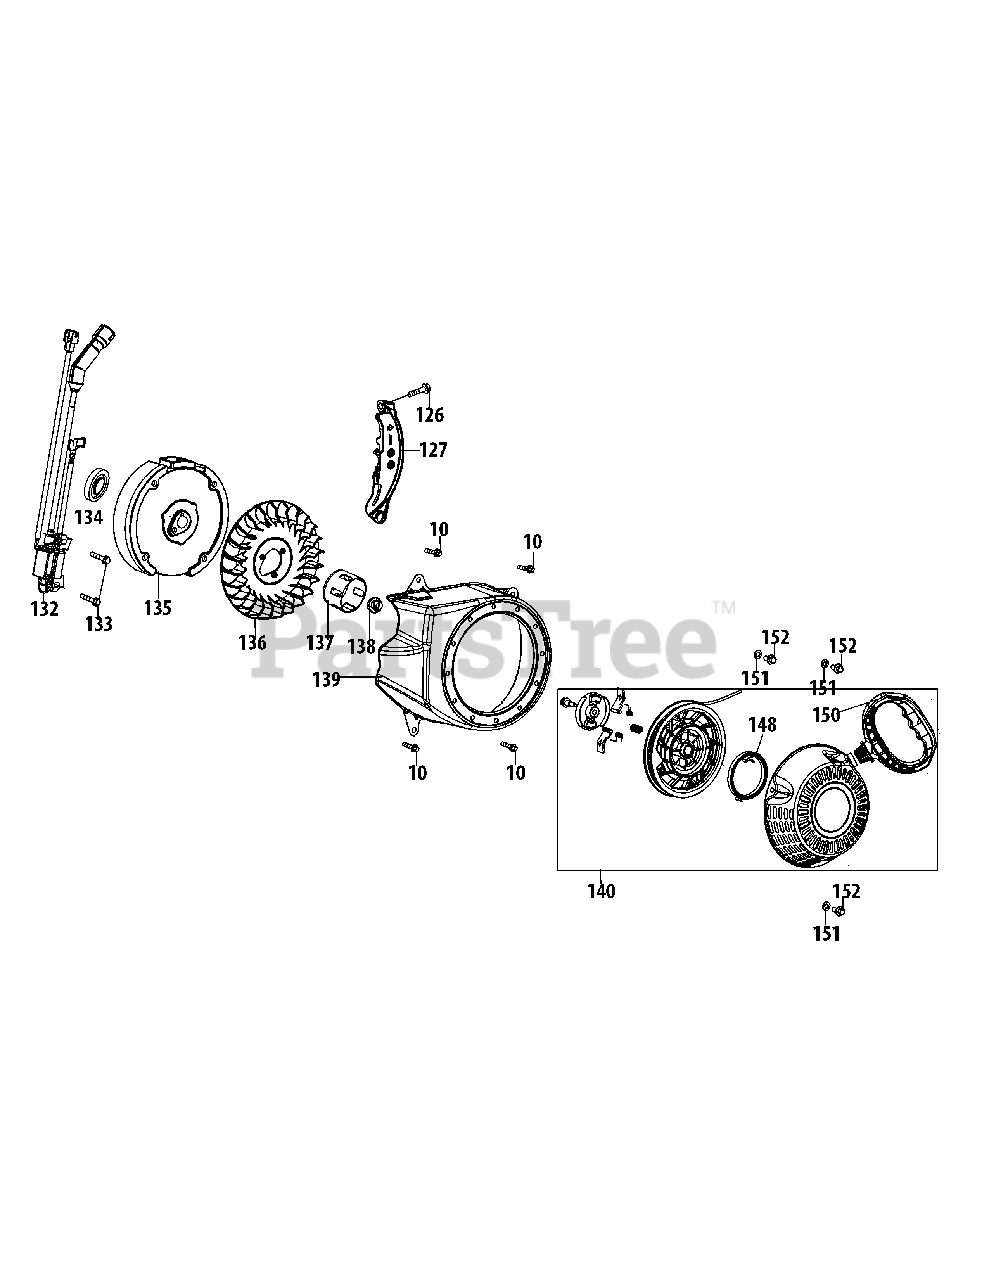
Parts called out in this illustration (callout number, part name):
10	Bolt M6×12
126	Bolt M6×20
127	Lower Shield
132	Ignition Module
133	Bolt M6×25
134	Oil Seal 25×41.25×6
135	Flywheel
136	Cooling Fan
137	Pulley, Starter
138	Flange Nut M14×1.5
139	Blower Housing
140	Recoil Starter
148	Recoil Spring
150	Starter Handle
151	Washer 6
152	Bolt M6×12
